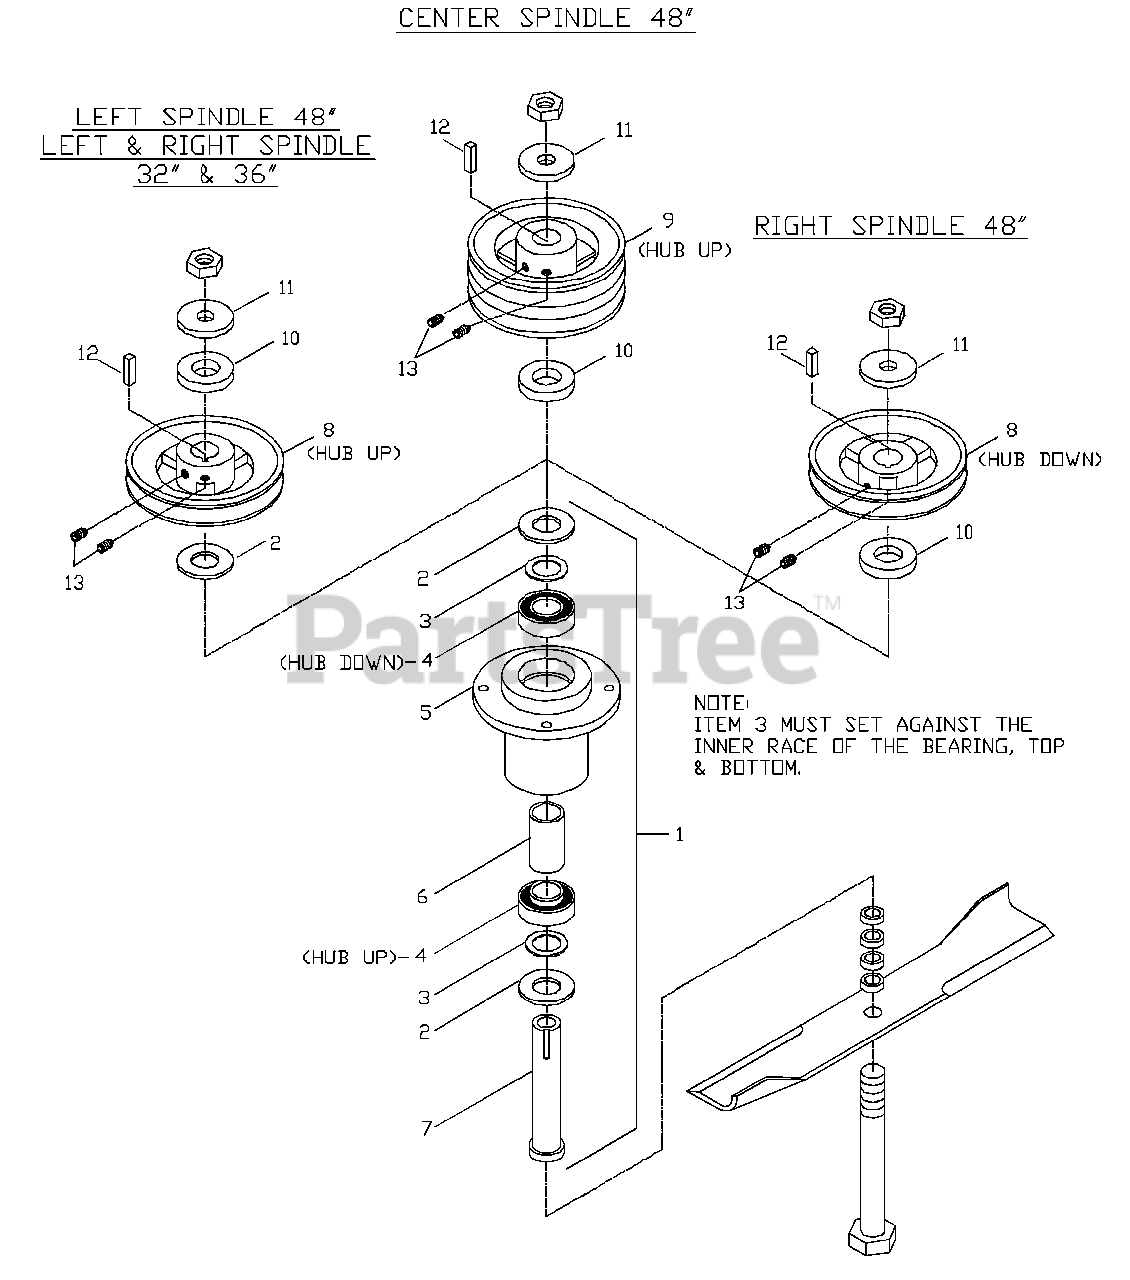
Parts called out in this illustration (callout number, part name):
1	CUTTER HOUSING ASM.
2	MACH. BUSING 10GA.
3	MACH. BUSING 18GA.
4	BEARING
9	DOUBLE PULLEY
10	3/8" SPACER
11	1/4" SPACER
12	KEY 1/4 SQ. X 1 1/8"
13	5/16 NYLOC SETSCREW
